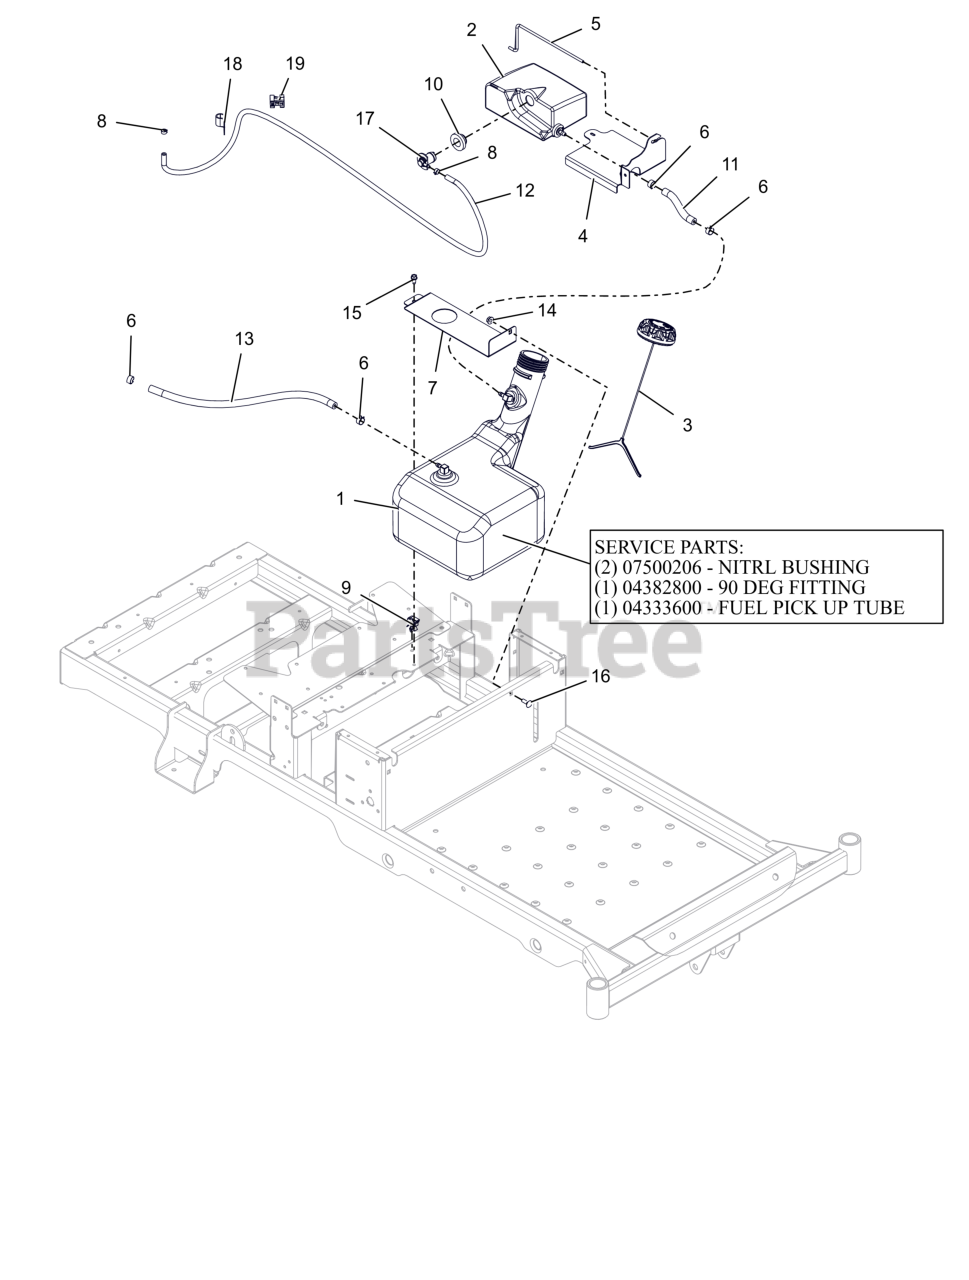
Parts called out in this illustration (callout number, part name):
1	ASM, FUEL TANK-ZOOM
1	BSHG-FLG .375X1.062X.625 NITR
1	FITTING, 90 DEG FUEL-PLASTIC
1	FUEL PICK UP TUBE
2	ASM, FUEL TANK - EXPANSION
3	CAP, FUEL VENT-IN 2.25" RATCH.
4	BRKT, EXPANSION TANK (ORANGE)
5	ROD, HOLDDOWN (BLACK)
6	CLAMP, FUEL LINE
7	BRKT, TANK STRAP
8	CLAMP-HOSE, SPRING .188
9	WIRE CLIP
10	GROMMET, REMOTE VENT NITRILE
11	HOSE, .25 LOW-PERM BULK GAS
12	HOSE, .188 LOW-PERM BULK GAS
13	HOSE, .25 LOW-PERM BULK GAS
14	NUT-LK-CTR-FLG .25-20 ZC120
15	SCR-TAP .25-20X.50 HWH ZCC
16	BLT, RHSN .25-20X.750 G5 ZCC
17	VALVE, 2-WAY
18	J-CLAMP
19	CLIP, T, .38-.50
